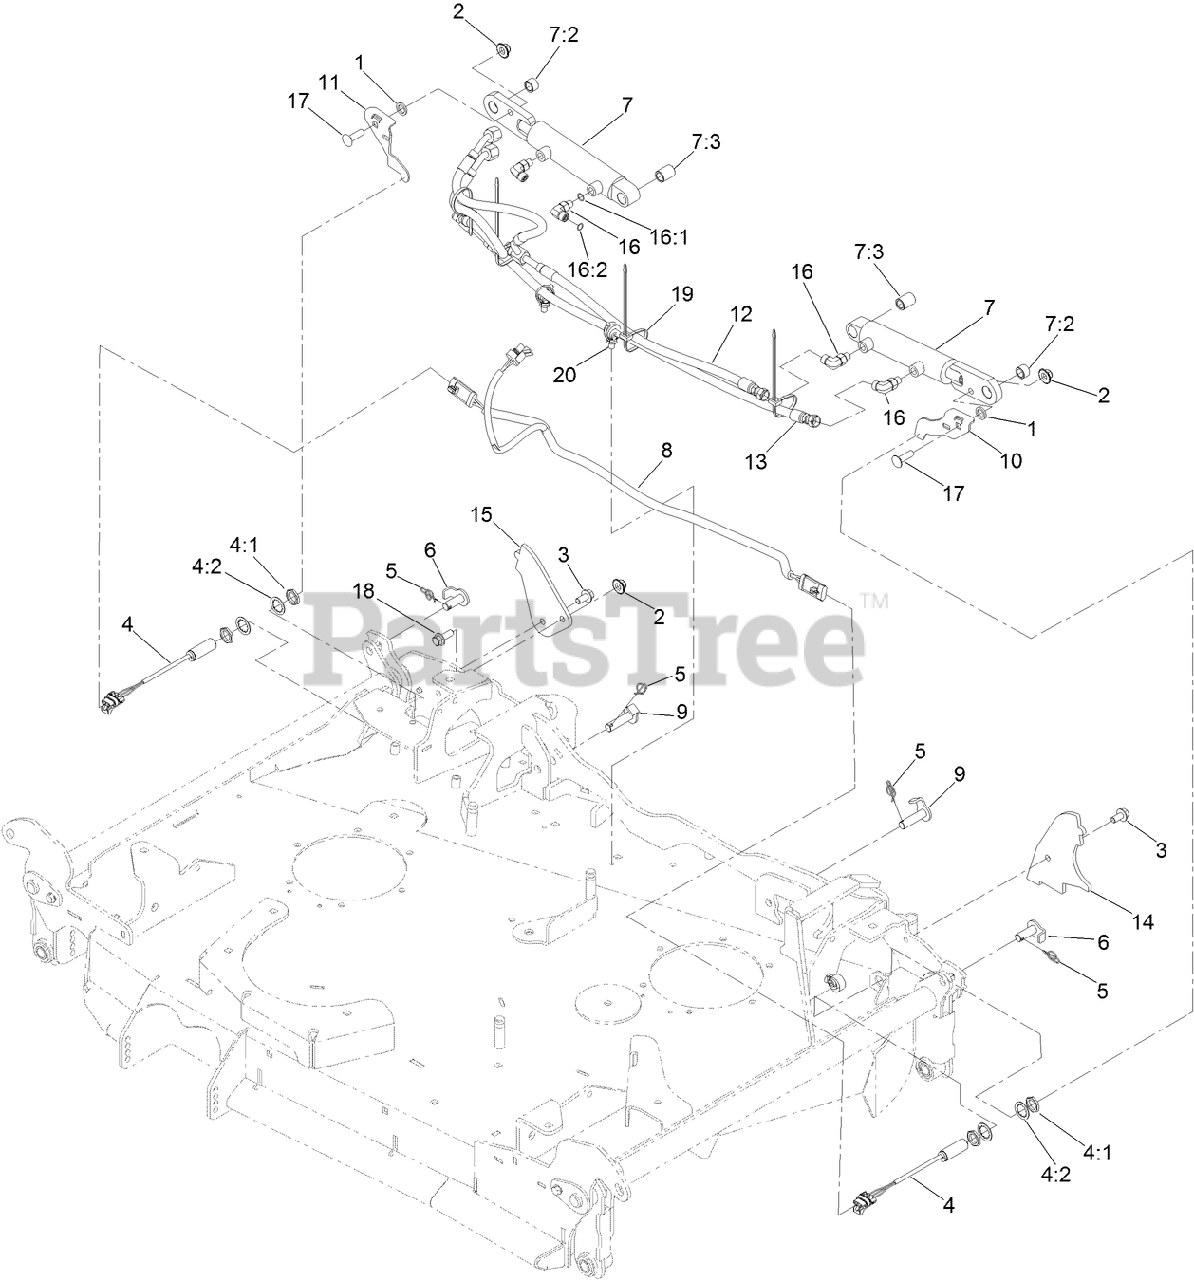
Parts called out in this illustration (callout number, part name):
1	WASHER
2	NUT-FLANGE, NI
3	SCREW-HWH
4	PROXIMITY SWITCH ASM
4:1	NUT-HEX
4:2	WASHER-LOCK, INTERNAL TOOTH
5	PIN-COTTER, LOCKING
6	EYE-PIN, CYLINDER
7	DECK FOLD CYLINDER ASM
7:2	BUSHING
7:3	BUSHING
8	HARNESS-WIRE
9	BASE-PIN, CYLINDER
12	HOSE ASM
13	HOSE ASM
14	BRACKET-DECK STOP, LH
15	BRACKET-DECK STOP, RH
16	FITTING-ELBOW, 90 DEG
16:1	O-RING
16:2	O-RING
17	SCREW-CARR
18	SCREW-HHF
19	TIE-CABLE
20	CLIP-TIE
